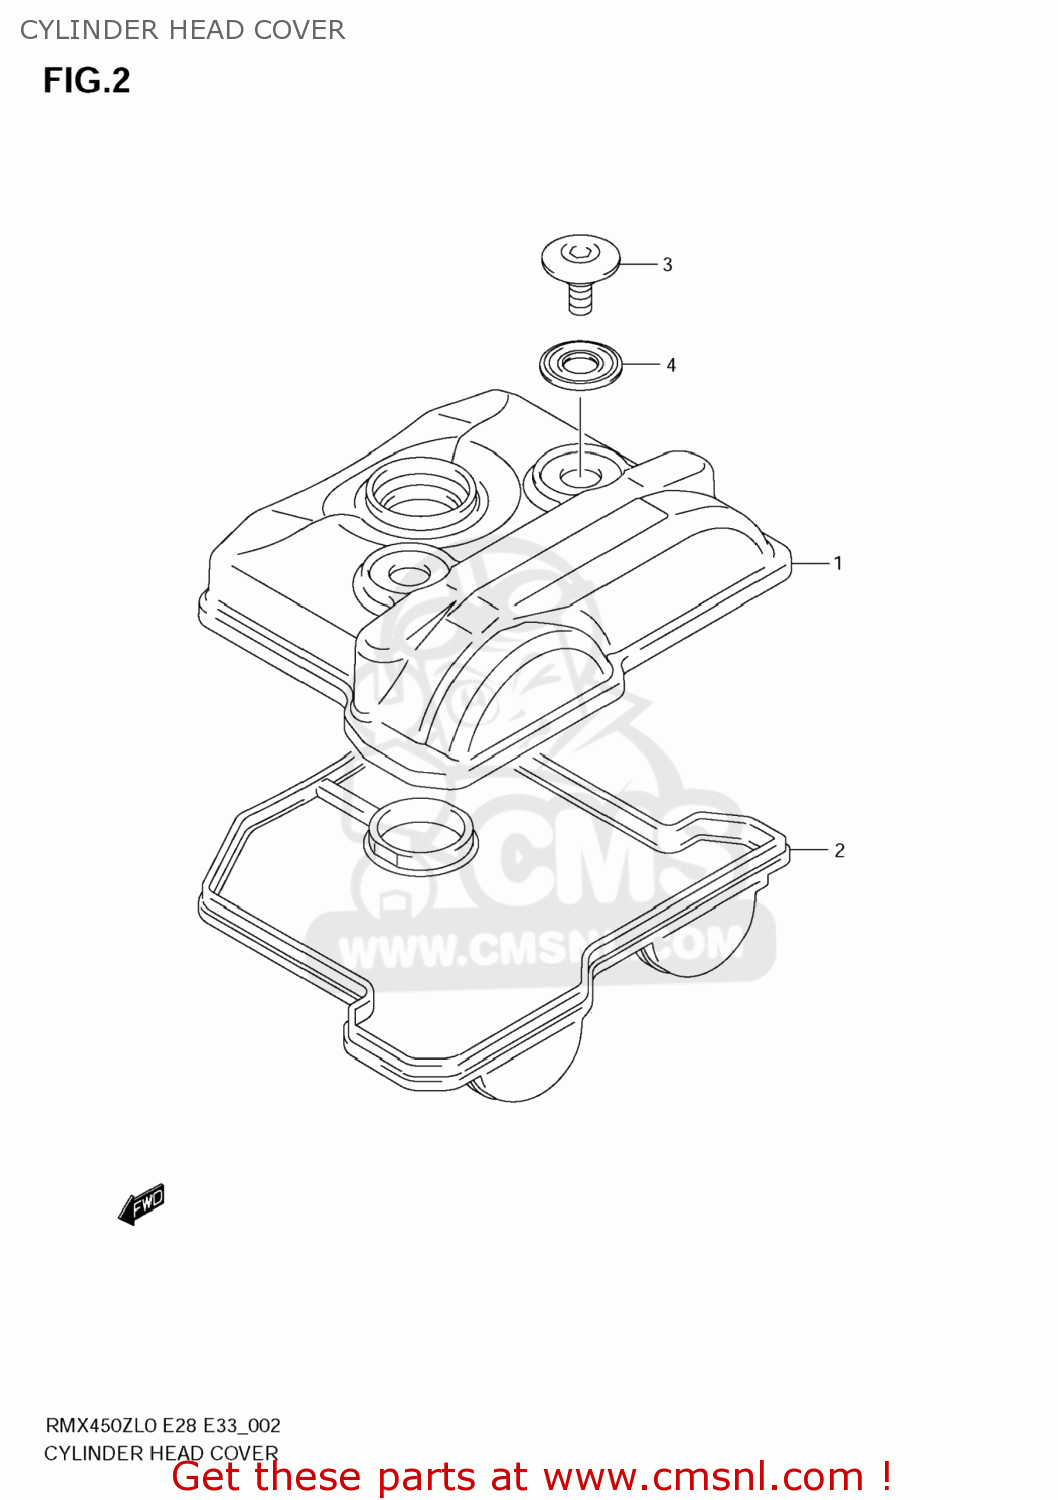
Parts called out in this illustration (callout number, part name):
1	COVER,CYLINDER HEAD
2	GASKET,CYL HEAD COVER (NAS)
3	BOLT(7X17.5)
4	WASHER,CYL HEAD COVER
